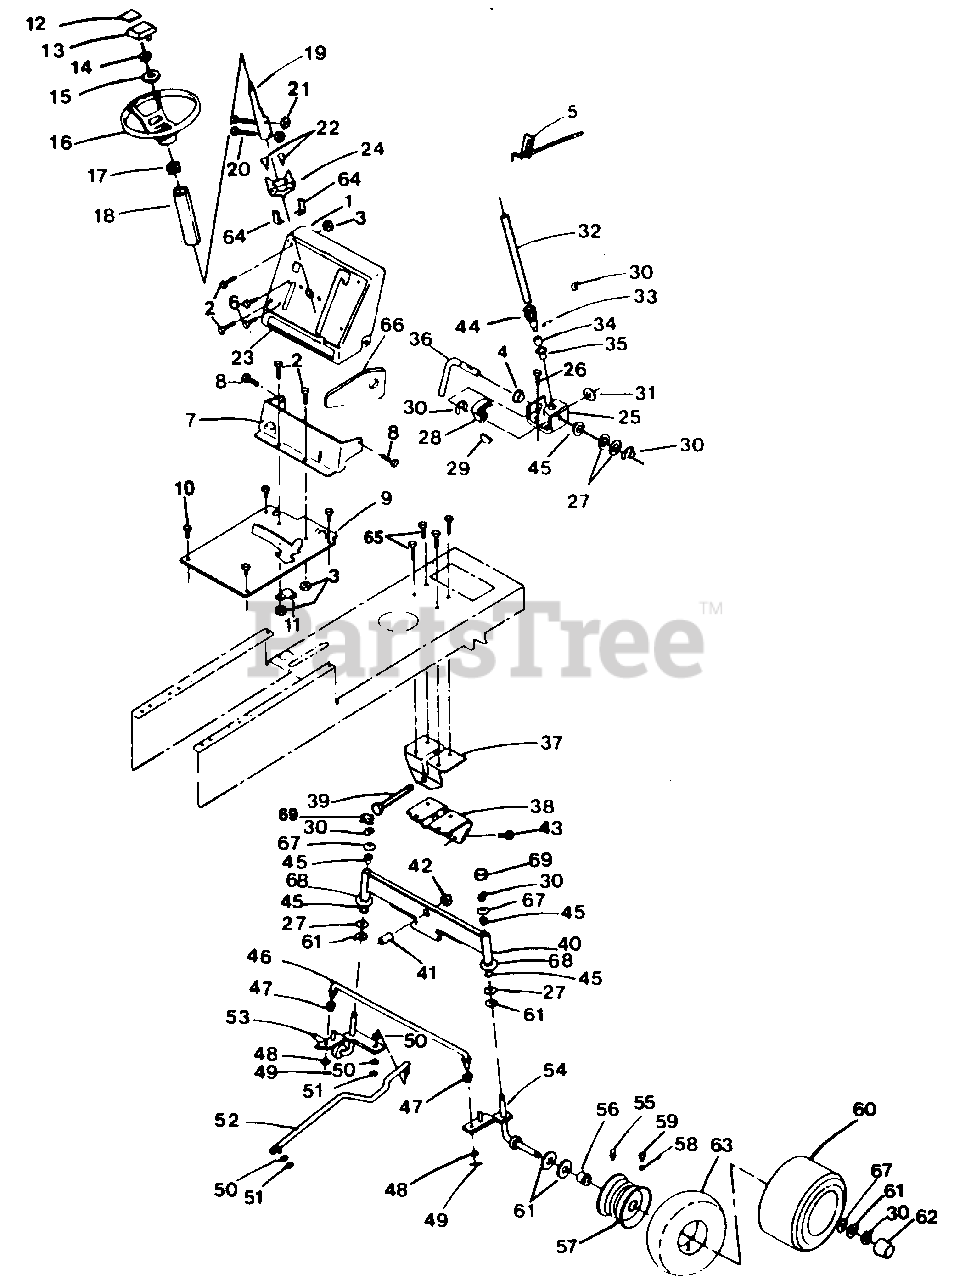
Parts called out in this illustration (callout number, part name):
1	Dash (AYP part number)
2	Truss Hd. Screw (AYP part number)
3	Keps Nut (AYP part number)
4	Snap-In Nyliner (AYP part number)
5	Throttle Control (AYP part number)
6	Thread Cutting Hex Screw (AYP part number)
7	Lower Dash (AYP part number)
8	Thread Cutting Hex Screw (AYP part number)
9	Saddle (AYP part number)
10	Thd. Roll. Washer Hd. Hex Screw (AYP part number)
11	Insulated Clip (AYP part number)
12	Steering Wheel Cap Decal (AYP part number)
13	Steering Wheel Insert (AYP part number)
14	Hex Jam Locknut (AYP part number)
15	Washer (AYP part number)
16	Steering Wheel (AYP part number)
17	Steering Wheel Adaptor (AYP part number)
18	Steering Sleeve (AYP part number)
19	Upper Steering Shaft (AYP part number)
20	Hex Bolt 3/8-16 x 1-1/4 (AYP part number)
21	Crownlock Nut
22	Self Tapping Hex Screw (AYP part number)
23	Operating Instruction Decal (AYP part number)
24	Steering Bushing (AYP part number)
25	Steering Bracket (AYP part number)
26	Thd. Roll. Washer Hd. Hex Screw (AYP part number)
27	Thrust Bearing (AYP part number)
28	Sector Gear (AYP part number)
29	Woodruff Key (AYP part number)
30	Klip Ring (AYP part number)
31	Hardened Washer (AYP part number)
32	Lower Steering Shaft (AYP part number)
33	Drive Pin (AYP part number)
34	Spacer (AYP part number)
35	Bushing (AYP part number)
36	Steering Rod (AYP part number)
37	Rear Saddle Support (AYP part number)
38	Front Saddle Support (AYP part number)
39	Hex Bolt (AYP part number)
40	Front Axle (AYP part number)
41	Front Axle Bearing Spacer (AYP part number)
42	Flange Locknut (AYP part number)
43	Thd. Roll. Washer Hd. Hex Screw (AYP part number)
44	Pinion Gear (AYP part number)
45	Bearing (AYP part number)
46	Tie Rod (AYP part number)
47	Bushing (AYP part number)
48	Washer (AYP part number)
49	Cotter Pin (AYP part number)
50	Lock Washer 3/8 (AYP part number)
51	Hex Nut 3/8-24 (AYP part number)
52	Drag Link (AYP part number)
53	L.H. Spindle (AYP part number)
54	R.H. Spindle (AYP part number)
55	Grease Fitting (AYP part number)
56	Flange Fitting
57	6 "Front Rim (Inc. 2 Each Key No. 56) (AYP part number)
58	Valve Cap (AYP part number)
59	Valve Stem (AYP part number)
60	Front Tire (AYP part number)
61	Washer (AYP part number)
62	Front Hub Cap (AYP part number)
63	Front Tube (Not furnished with tractor)
64	Steering Retainer (AYP part number)
65	Special Screw (AYP part number)
66	Clutch Lever Stop Mower (AYP part number)
67	Washer (AYP part number)
68	Washer (AYP part number)
69	Spindle Cap (AYP part number)
